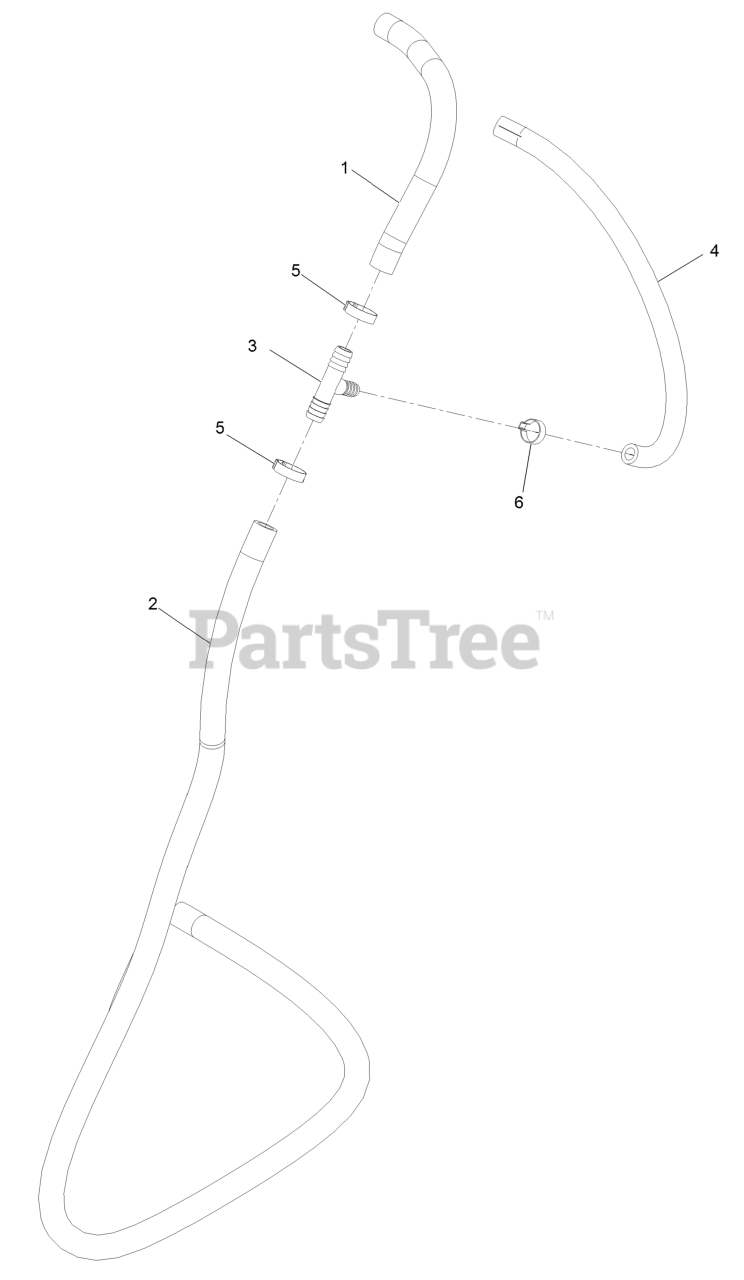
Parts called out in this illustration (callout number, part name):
1	HOSE-WATER
2	HOSE-WATER
3	CONNECTOR-TEE
4	HOSE-WATER
